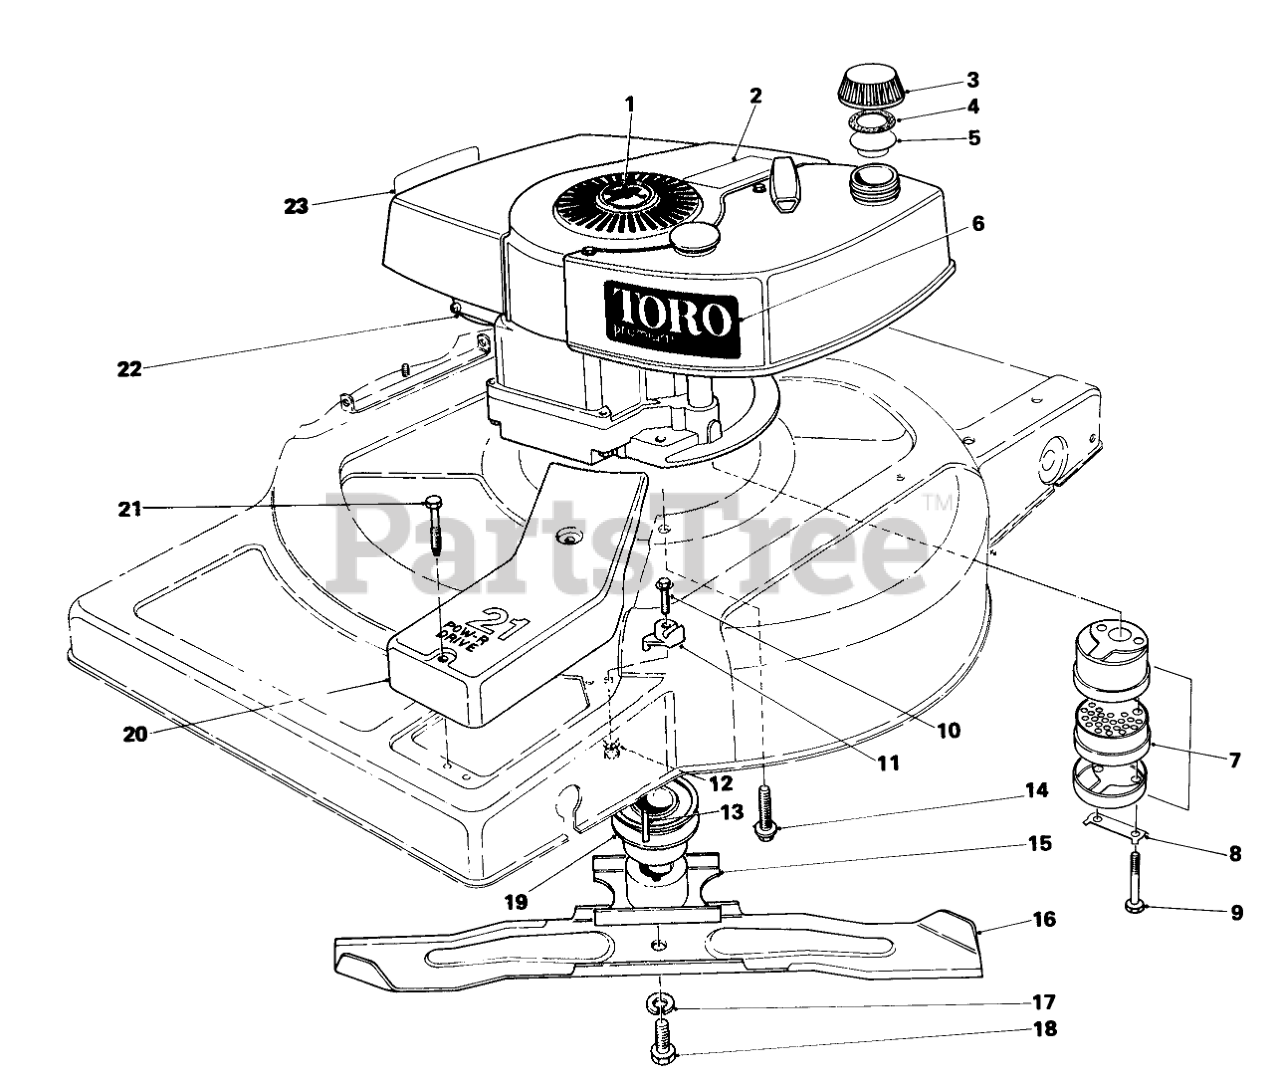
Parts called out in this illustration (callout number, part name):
1	PLUG BUTTON
2	Decal Lockout
3	Gas Cap (Incl. Ref. #4 & 5)
4	GASKET
5	GAS CAP BAFFLE
6	Decal
7	Muffler Assembly (Incl. Ref. #8&9)
8	CLIP - LOCKING
9	SCREW-HH
11	CABLE BOSS
12	SPEED NUT
13	KEY-SQUARE
14	SCREW-HWHTF
15	Blade Retainer
16	Blade
17	WASHER-LOCK
18	SPECIAL SCREW
19	Pulley
20	COVER BELT
21	SCREW-HHFTF
22	Engine
23	Decal-Maintenan
